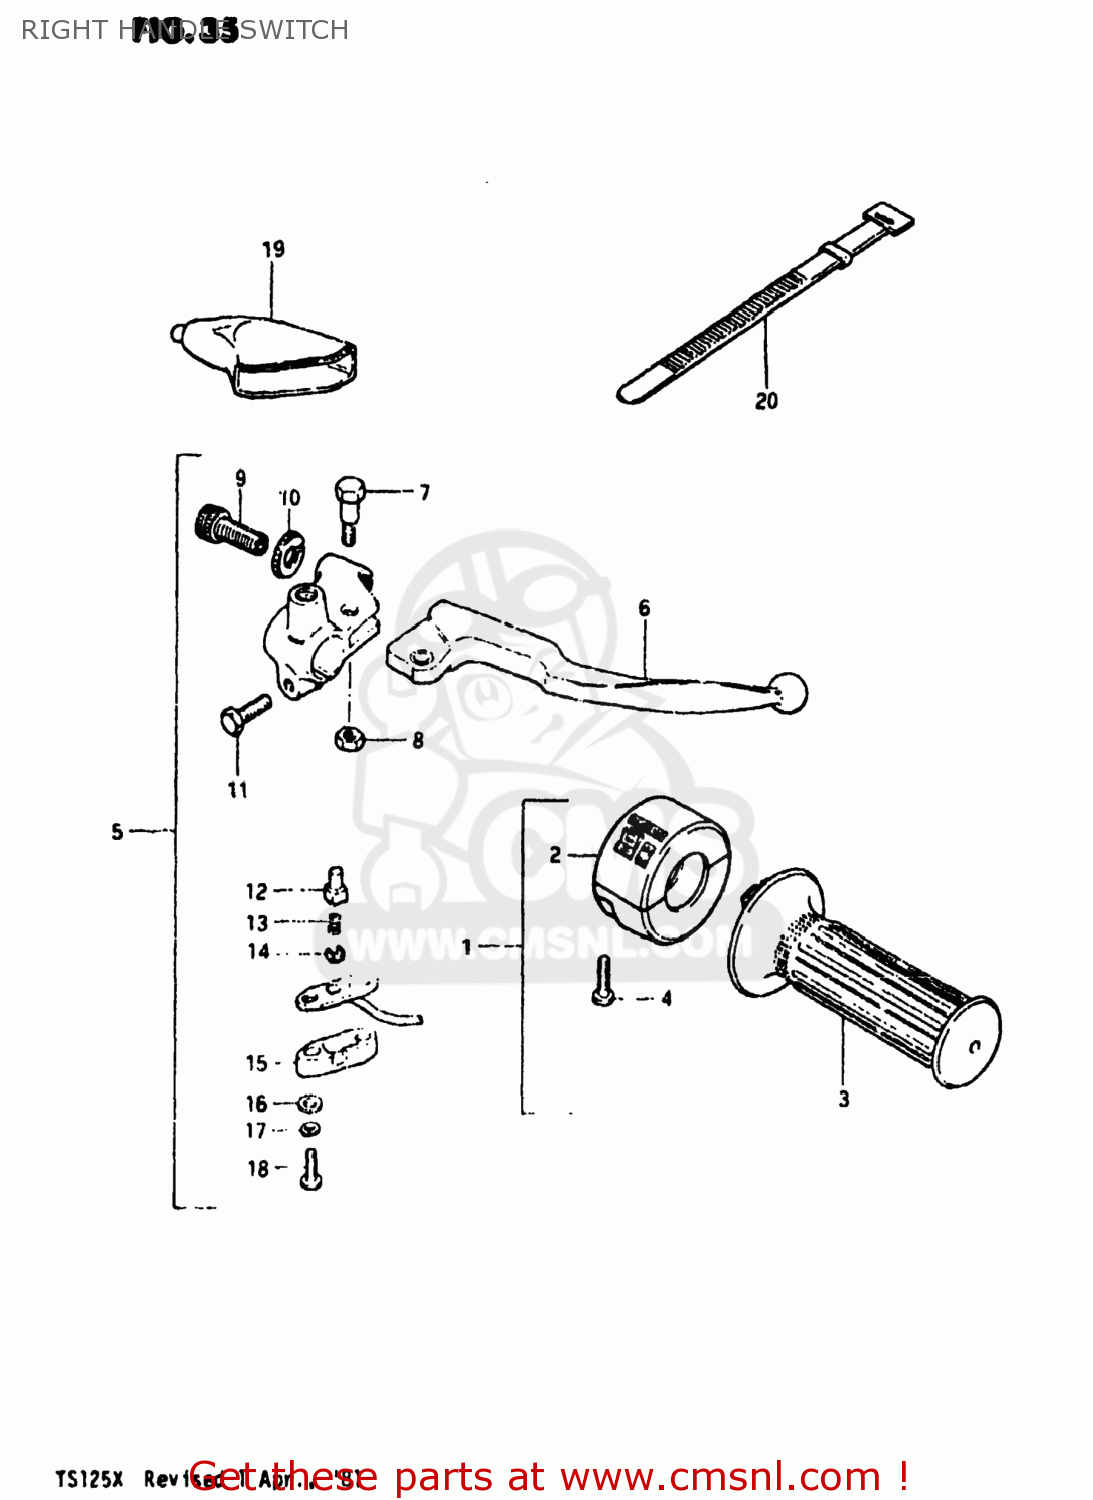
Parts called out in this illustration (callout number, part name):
1	CASE ASSEMBLY,THROTTLE
2	CASE ASSY,THROTTLE
3	GRIP,THROTTLE
4	SCREW
5	LEVER ASSY,BRAKE
6	LEVER,BRAKE
7	BOLT,LEVER
8	NUT 6MM
9	ADJUSTER,CABLE
10	NUT,CABLE ADJUSTER
11	BOLT
12	HOLDER
13	SPRING
14	PLATE
15	COVER,FR BK TERMINAL BASE
16	WASHER
17	LOCK WASHER
18	SCREW
19	COVER,CLUTCH LEVER
20	CLAMP(L:120)
